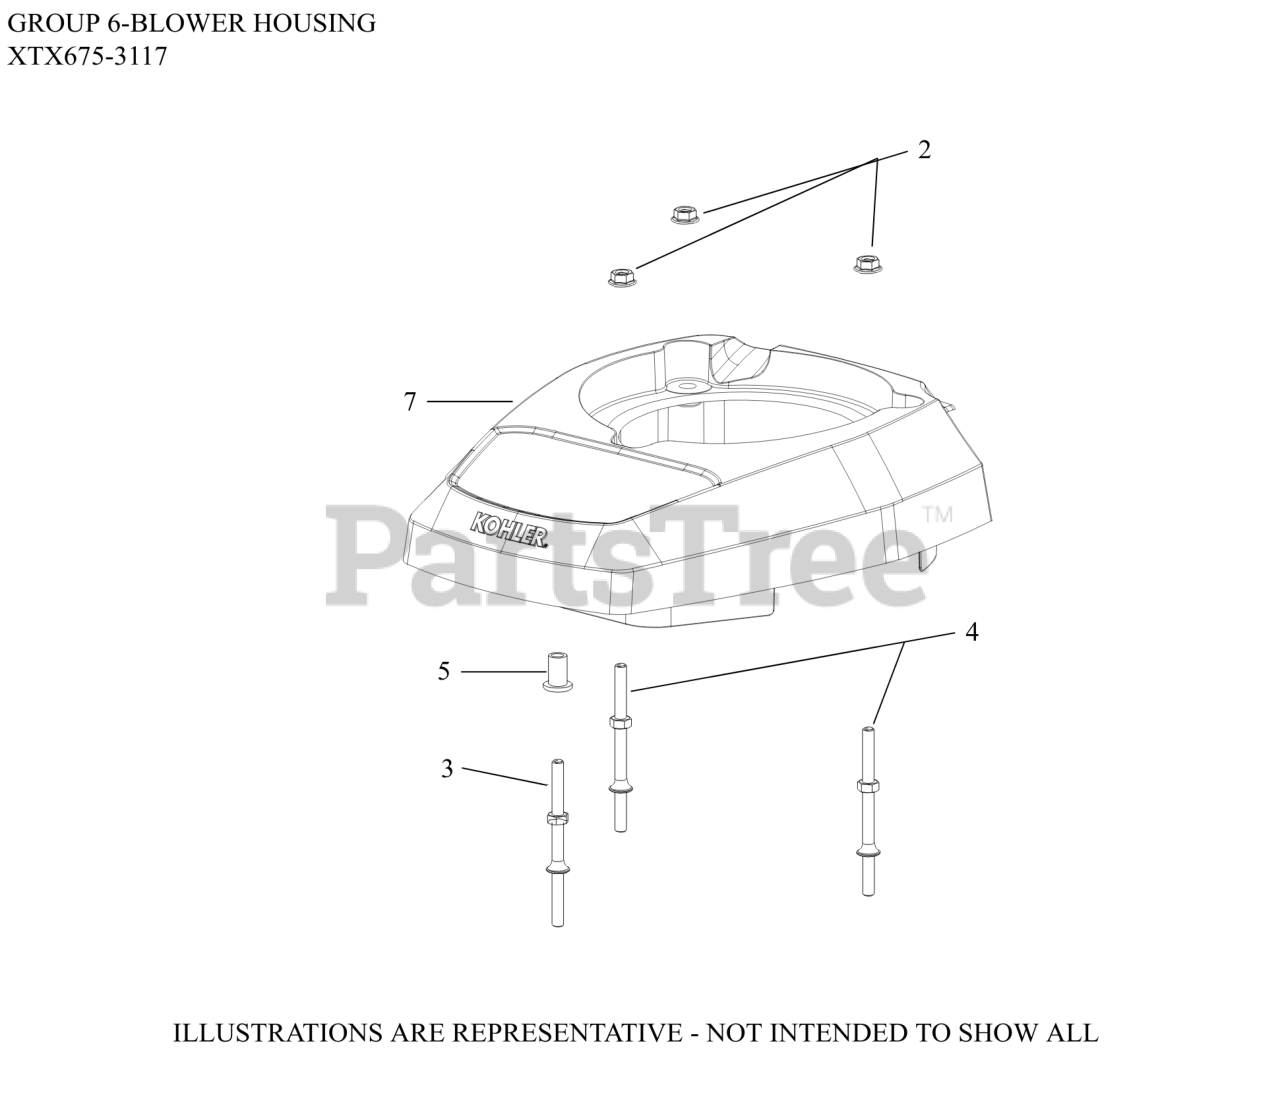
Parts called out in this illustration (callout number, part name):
2	NUT, HEX FLANGE (M6) - USE 14 100 16-S
3	STUD-USE 14 072 25-S
4	STUD-USE 14 072 26-S
7	COVER, ENGINE
